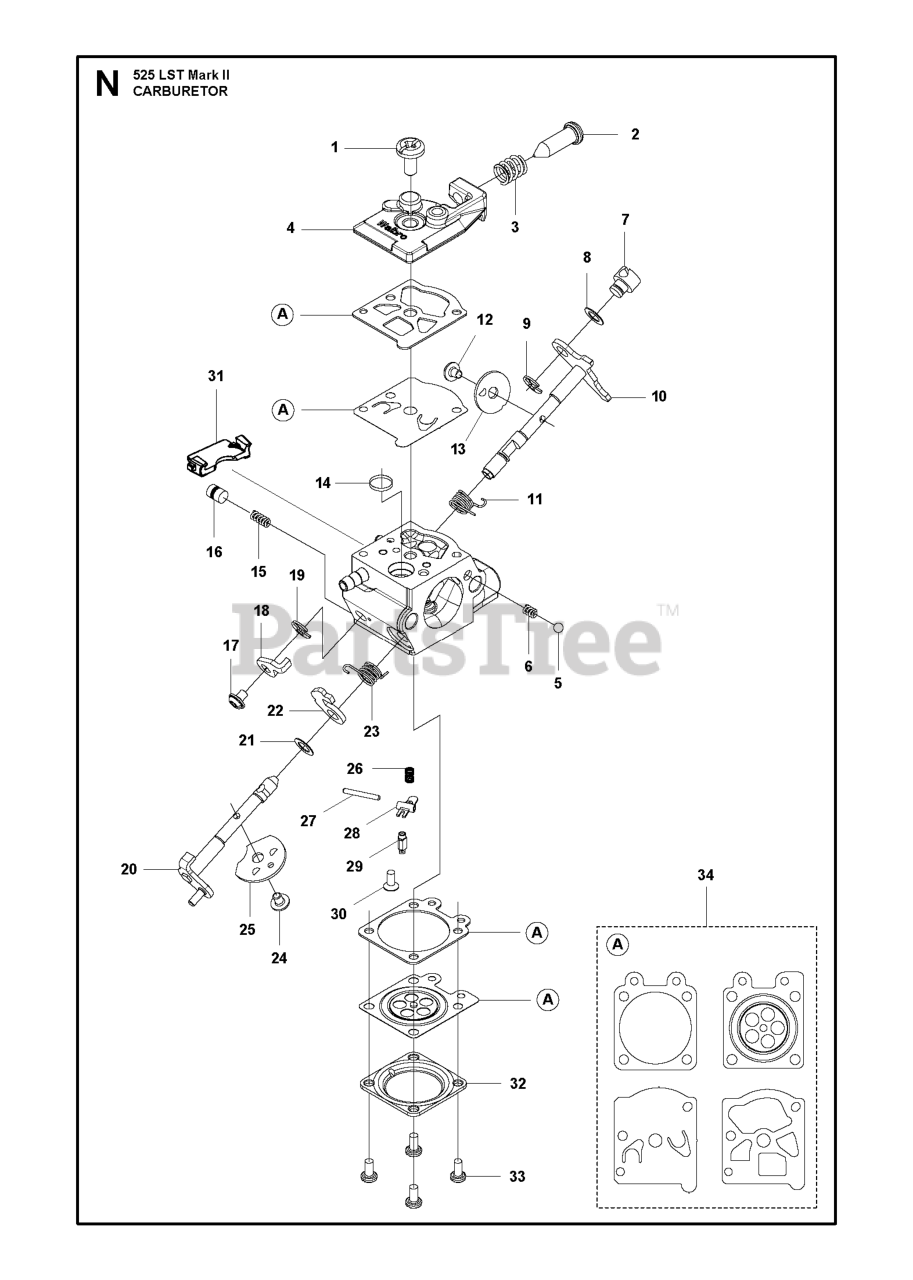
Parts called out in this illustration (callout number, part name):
2	SCREW, IDLE
4	COVER PUMP
6	CHOKE SPRING
10	SHAFT ASSEMBLY,THROTTLE
13	VALVE, THROTTLE
14	SCREEN
18	LEVER THROTTLE
20	SHAFT ASSEMBLY,CHOKE
25	VALVE CHOKE
29	VALVE INLET
33	SCREW ASSY
34	GASKET KIT
